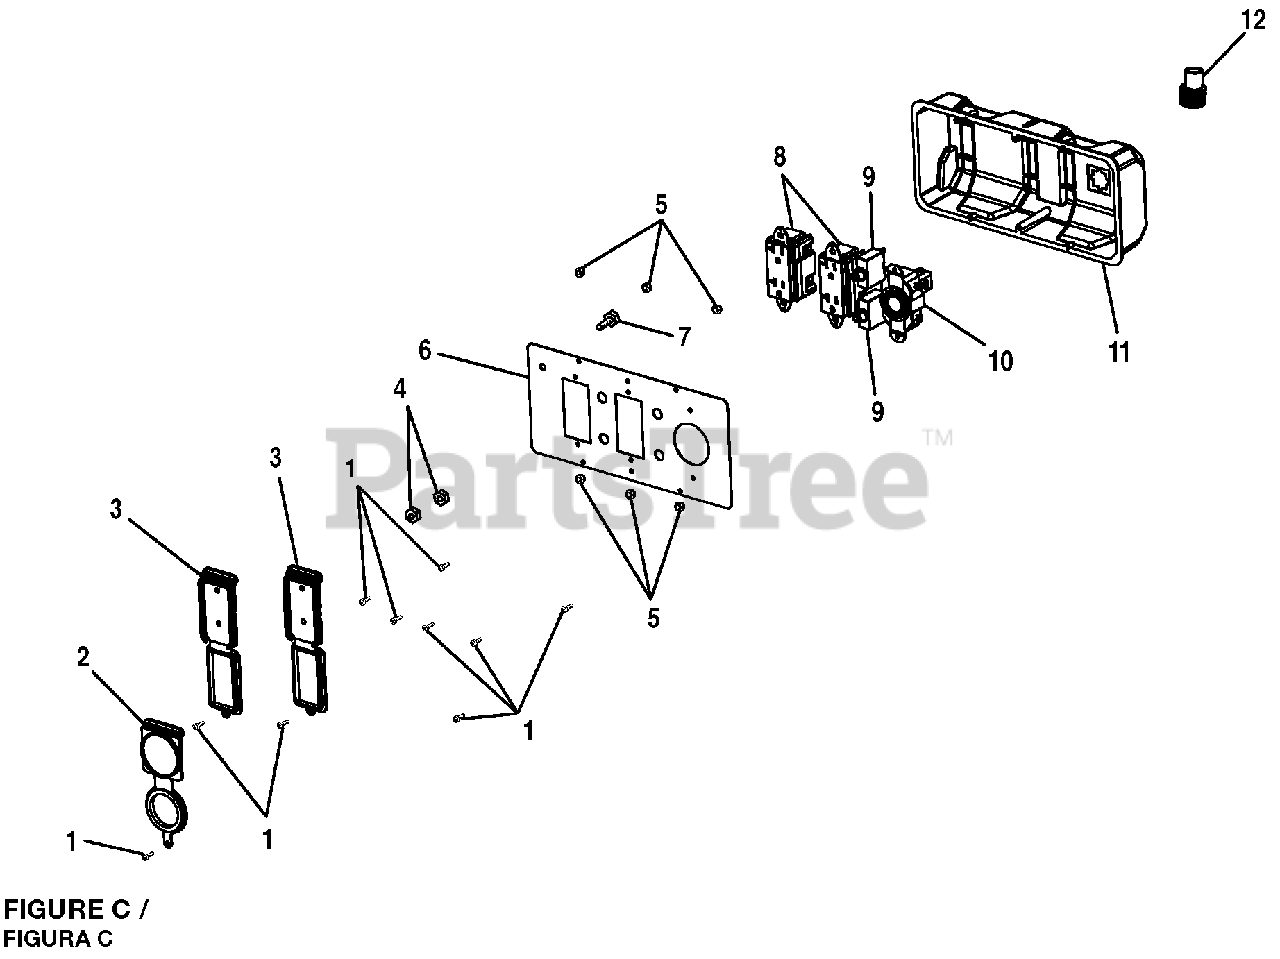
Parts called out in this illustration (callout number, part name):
1	Screw (6-20 x 3/8 in.)
2	Outlet Cover (240 Volt)
3	Outlet Cover (120 Volt)
4	Hex Nut (1/4-20)
5	Nut (M6-32)
6	Cover Plate
7	Screw (1/4-20 x 5/8 in., Hex Hd.)
8	Duplex Receptacle (120 Volt)
9	Circuit Breaker (20 Amp, 125 Volt)
10	Twist Lock Receptacle (120/240 Volt, 20 Amp)
11	Rear Control Panel
12	Rubber Boot
13	Control Panel Label
